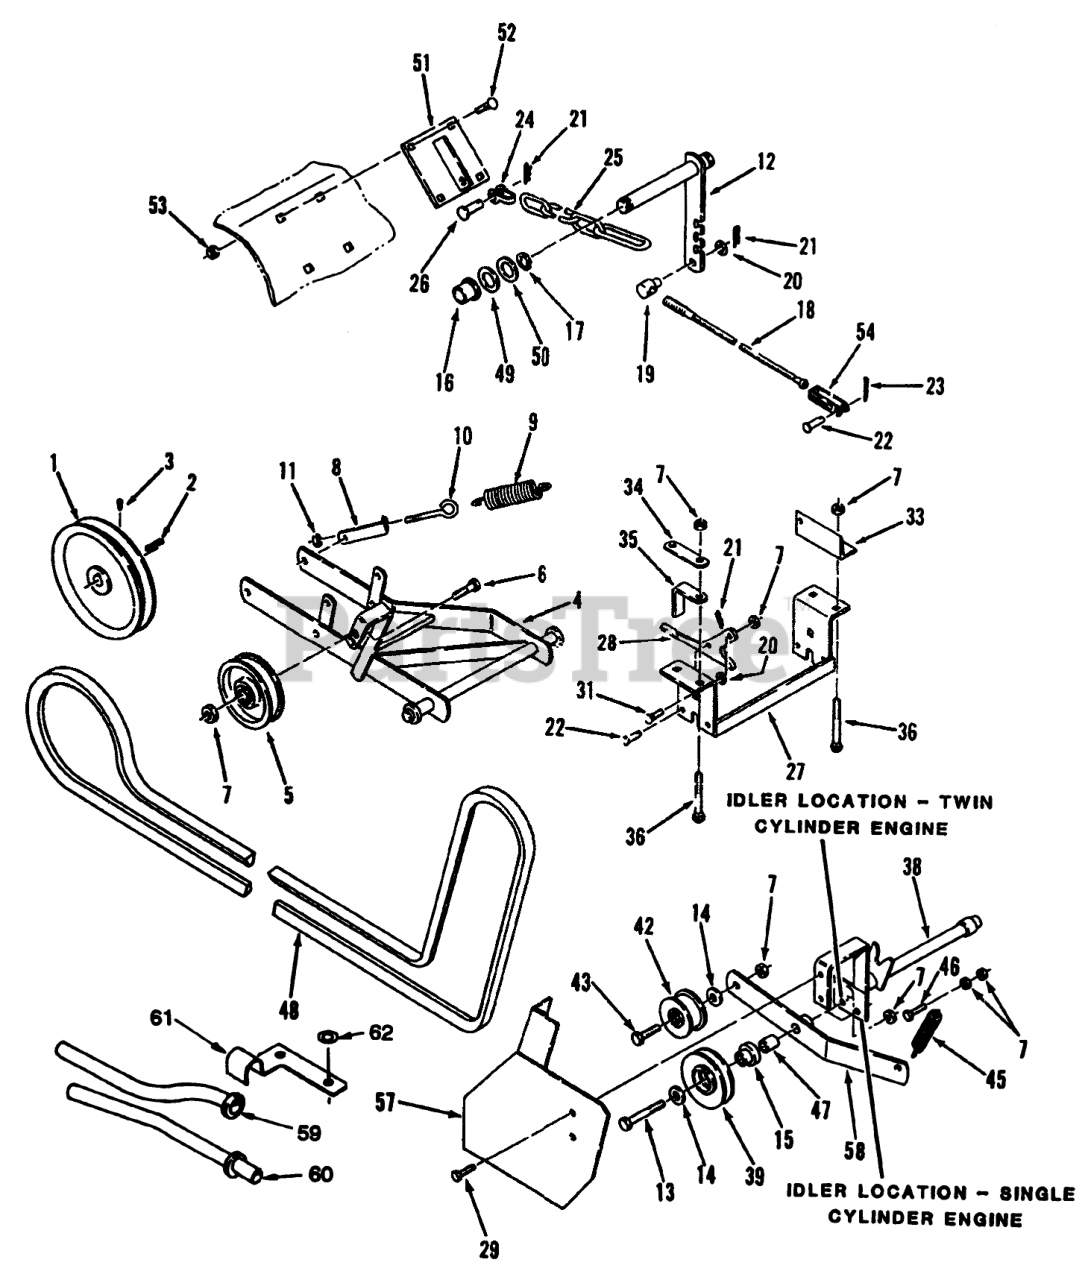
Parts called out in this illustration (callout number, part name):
1	Pulley
2	KEY-STRAIGHT
3	Set Screw
4	Hitch
5	Flat Idler
6	SCREW-HH
7	NUT-HEX
8	Bracket-Spring
9	SPRING
10	EYEBOLT
11	NUT-LOCK, NI
12	ASSY LEVER R
13	SCREW-HH
14	WASHER-FLAT
15	SPACER
16	BUSHING-BRONZE
17	E-RING
18	CABLE
19	TRUNNION-CLUTCH ROD
20	WASHER-FLAT
21	Hairpin
22	Pin
23	Cotter Pin
24	CLEVIS ASM
25	CHAIN LIFT
26	Clevis Pin
27	Bracket
28	PLATE-LATCHING
29	Bolt
31	BOLT-CARR
33	LINK-BRACKET R
34	BRACKET-REAR LINK MOUNTING
35	SPACER-BRACKET
36	SCREW-CARR
38	ASSY SUPPORT R
39	Pulley-V
42	IDLER PULLEY
43	HEX HD CAP SCREW
45	SPRING-BRAKE
46	SCREW-HH
47	SPACER
48	V-BELT
49	WASHER
50	WASHER-SHIM
51	Lift Plate
52	BOLT-CARR
53	NUT-LOCK, NI
54	CLEVIS-SHORT
57	ASM: FRONT IDLER R
58	Arm-Idler
59	TUBE-CONDUIT R
60	Conduit-Mech. Trans.
61	CLAMP-CONDUIT R
62	WASHER
